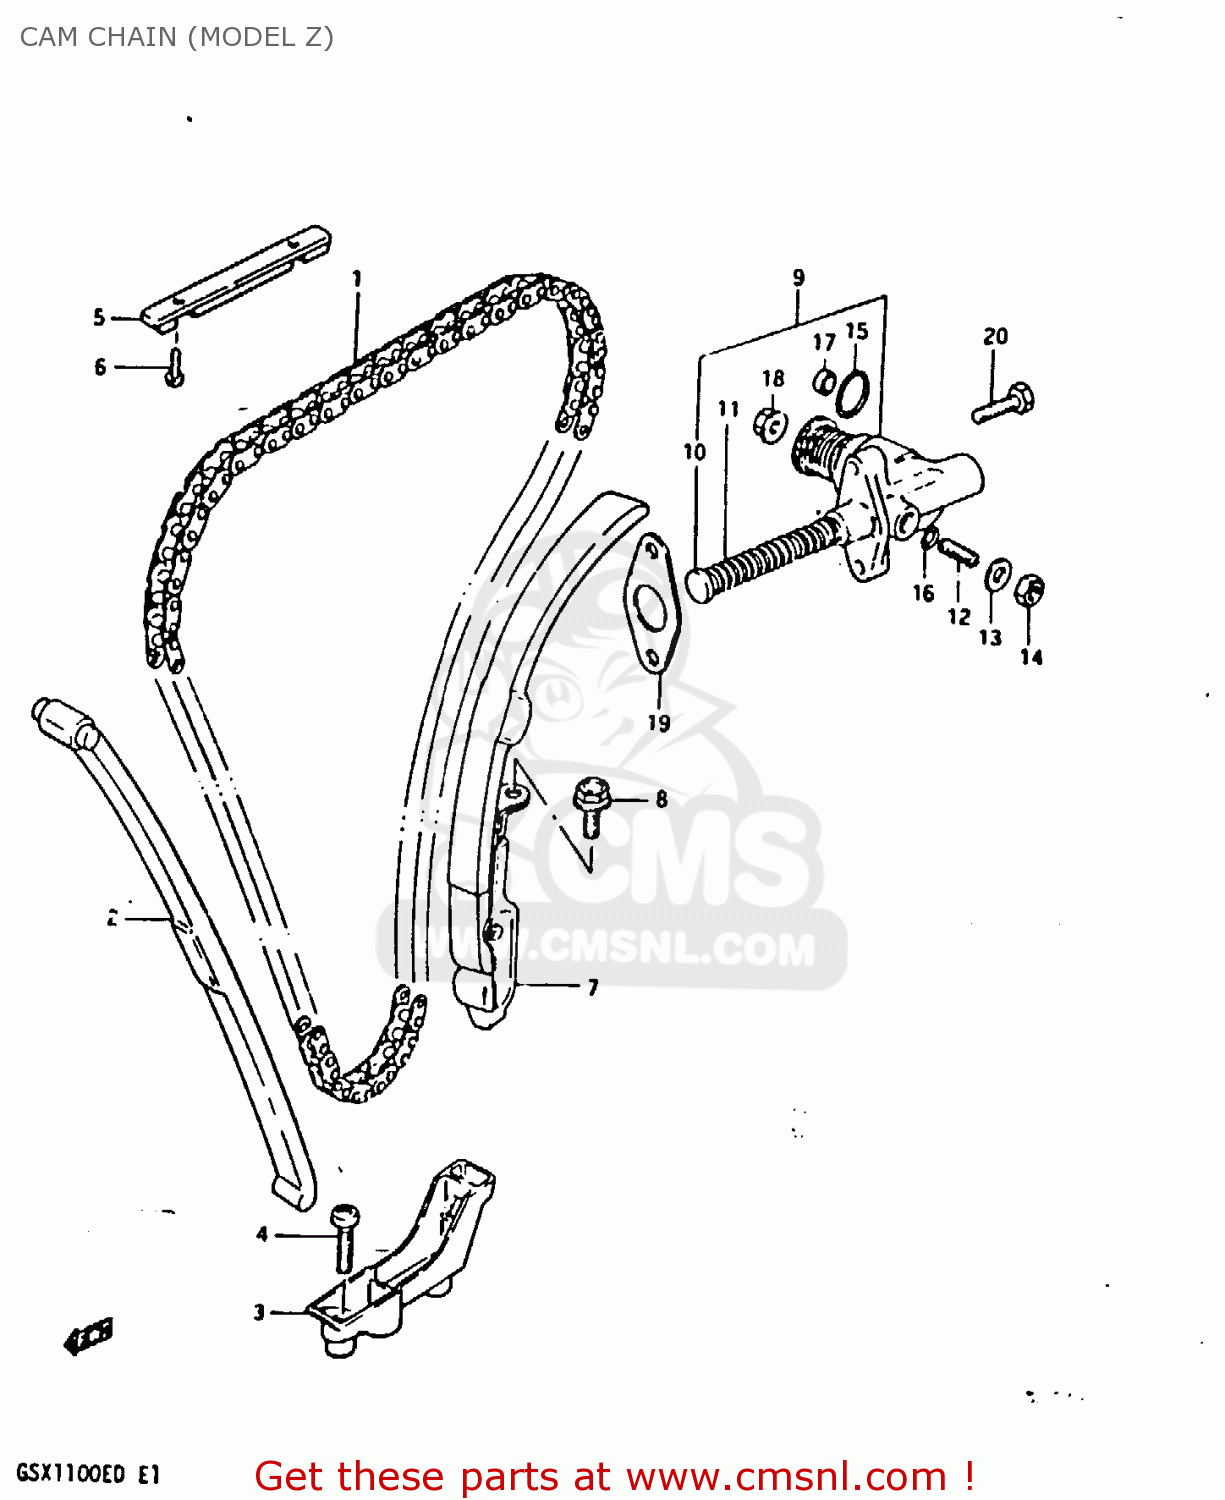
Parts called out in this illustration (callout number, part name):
1	CHAIN,CAMSHAFT DRIVE
2	GUIDE,CAM CHAIN NO.1
3	HOLDER,CAM CHAIN GUIDE
4	SCREW
5	GUIDE,CAM CHAIN
6	SCREW
7	TENSIONER,CAM CHAIN
8	BOLT
9	ADJUSTER,CAM CHAIN TENSIONER
10	ROD,PUSH
11	SPRING
12	SCREW
13	WASHER
14	NUT
15	O-RING
16	O-RING
17	OIL SEAL
18	NUT
19	GASKET,TENSIONER ADJUSTER (MCA)
20	SCREW (6X25)
